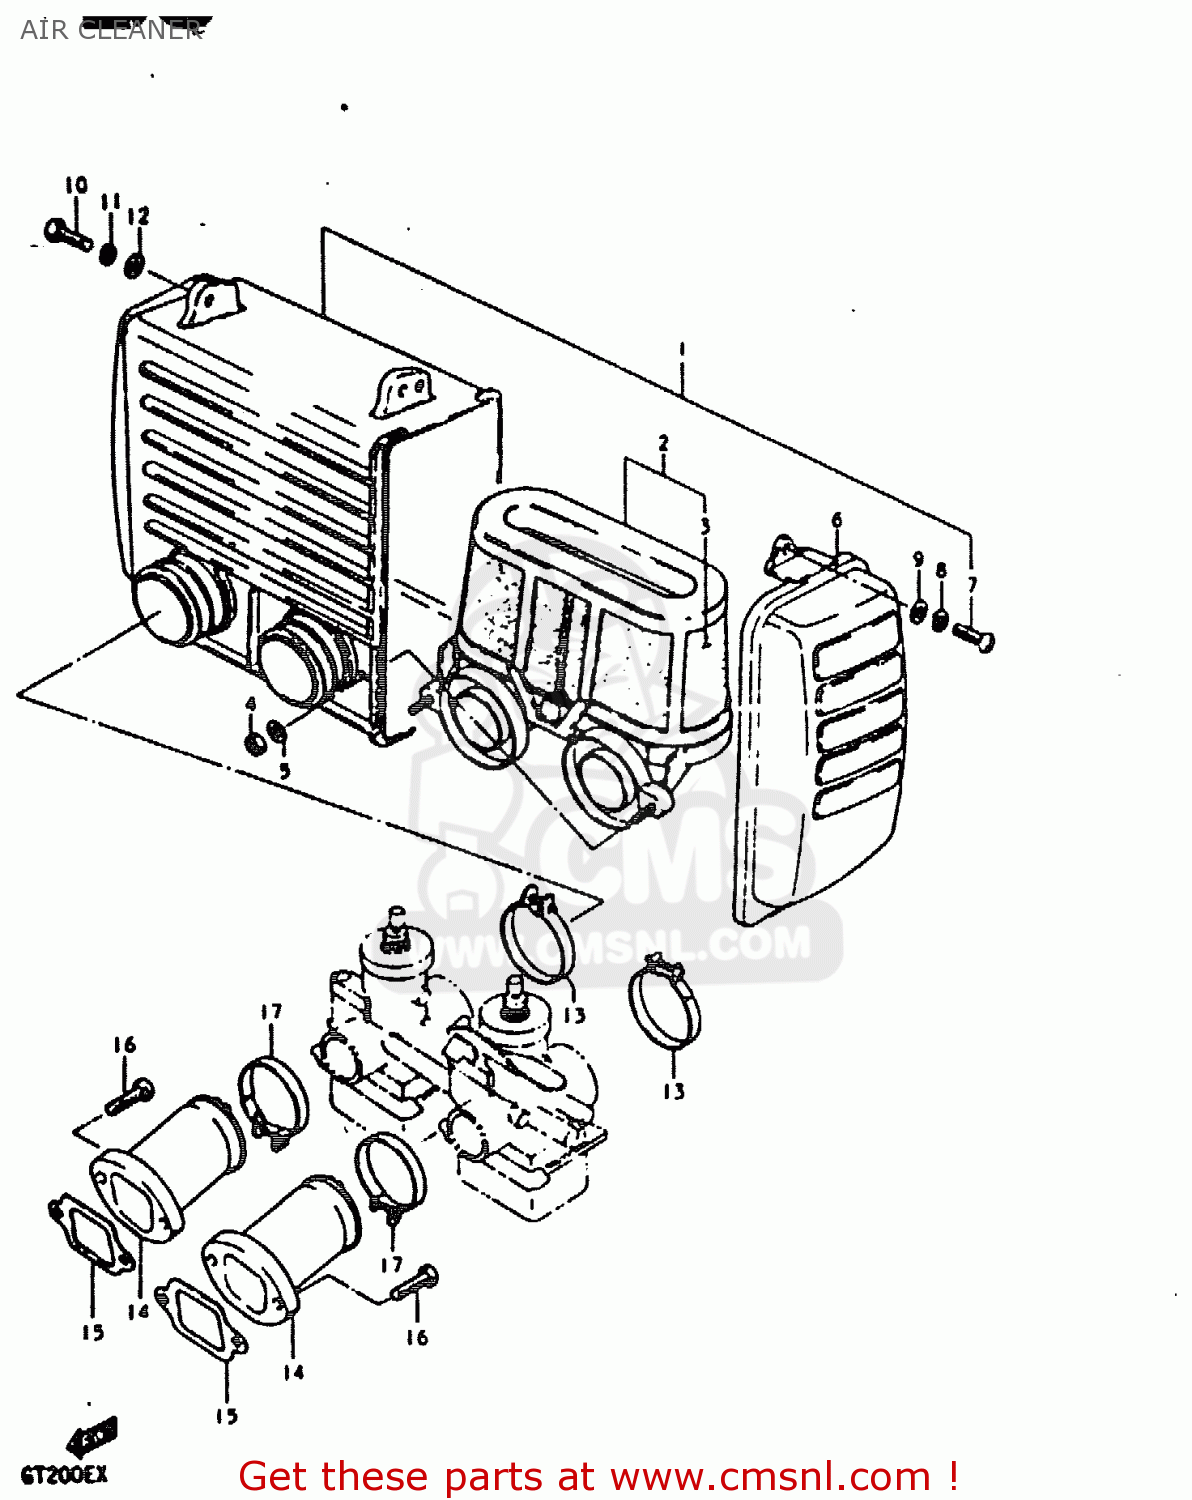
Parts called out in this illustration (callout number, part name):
1	CLEANER ASSY, AIR
2	FILTER ASSY
3	FILTER
4	NUT
5	WASHER
6	CAP
7	SCREW
8	LOCK WASHER
9	WASHER
10	SCREW
11	LOCK WASHER
12	WASHER
13	CLAMP
14	PIPE, INTAKE
15	GASKET,INTAKE PIPE (NAS)
16	SCREW
17	CLAMP
